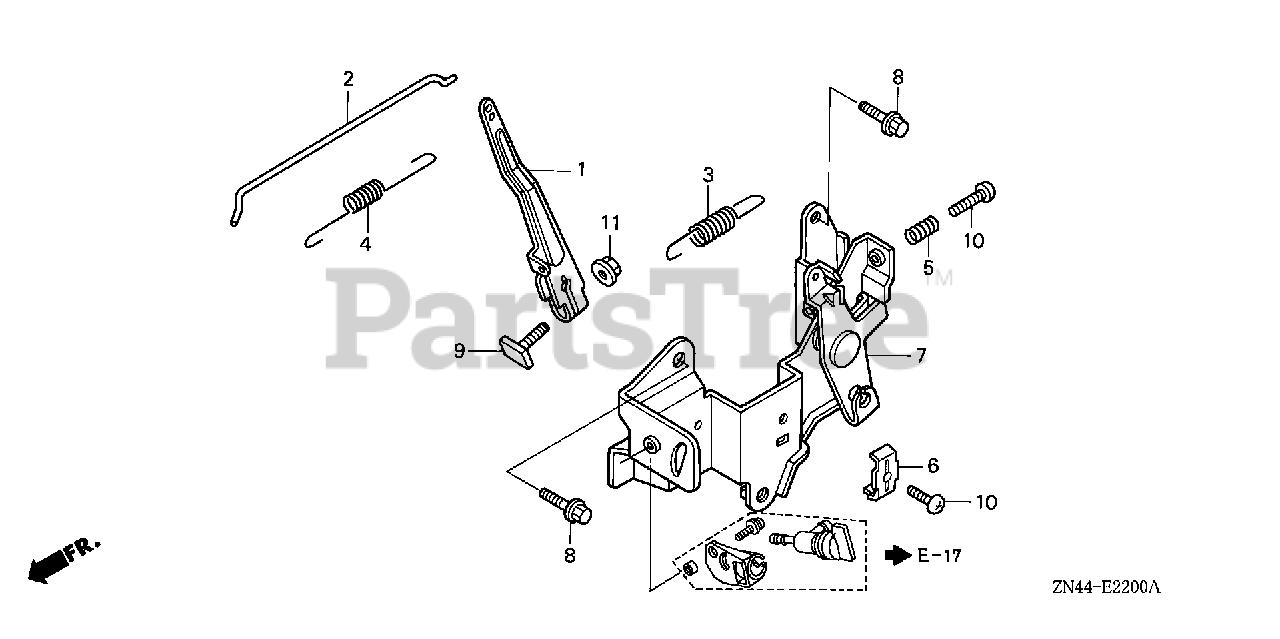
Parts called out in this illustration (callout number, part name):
1	ARM, GOVERNOR
2	ROD, GOVERNOR
3	SPRING, GOVERNOR
4	SPRING, THROTTLE RETURN
5	SPRING, CONTROL ADJUSTING
6	HOLDER, CABLE
7	BASE, CONTROL
8	BOLT, FLANGE (5X12)
9	BOLT, GOVERNOR ARM
10	SCREW, PAN (5X20)
11	NUT, FLANGE (6MM)
